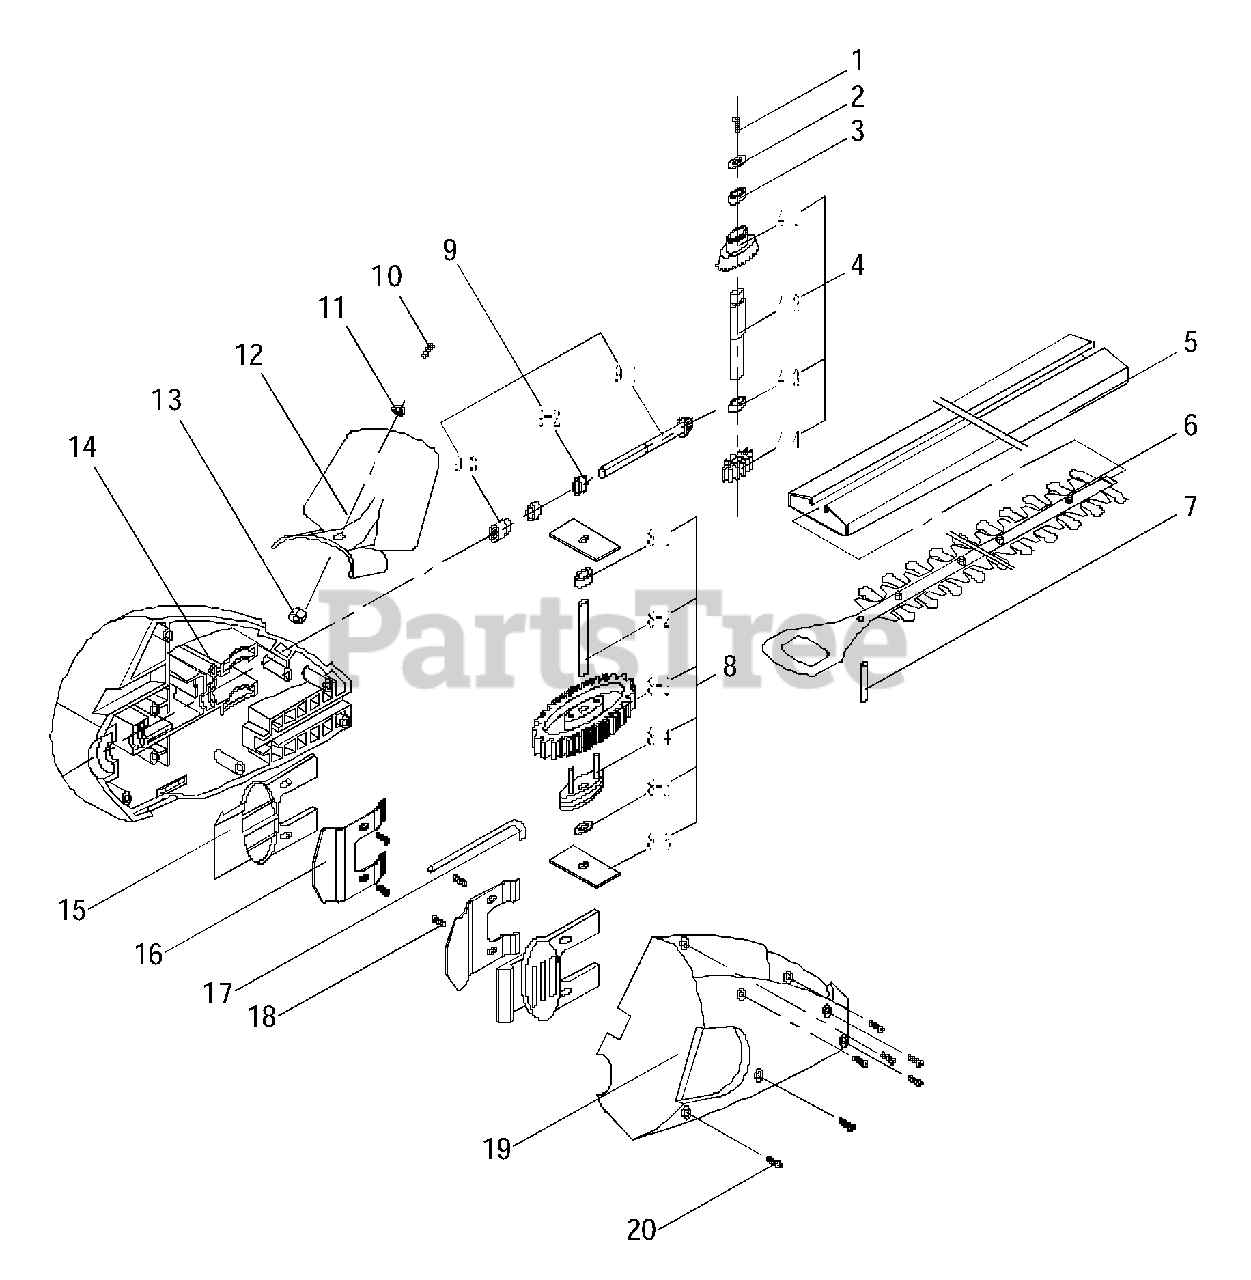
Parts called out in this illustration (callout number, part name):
1	SCREW
4	TRANSMISSION ASS'Y
4	TRANSMISSION SHAFT
4	GEAR PINION
5	BLADE COVER
8	RECIPROCAL ASS'Y
8	SHAFT SLEEVE
8	FIXED LINK
8	GEAR WHEEL
9	GEAR SHAFT ASS'Y
9	GEAR SHAFT
9	JOINTING SLEEVE
10	SCREW
14	HOUSING (L)
19	HOUSING (R)
